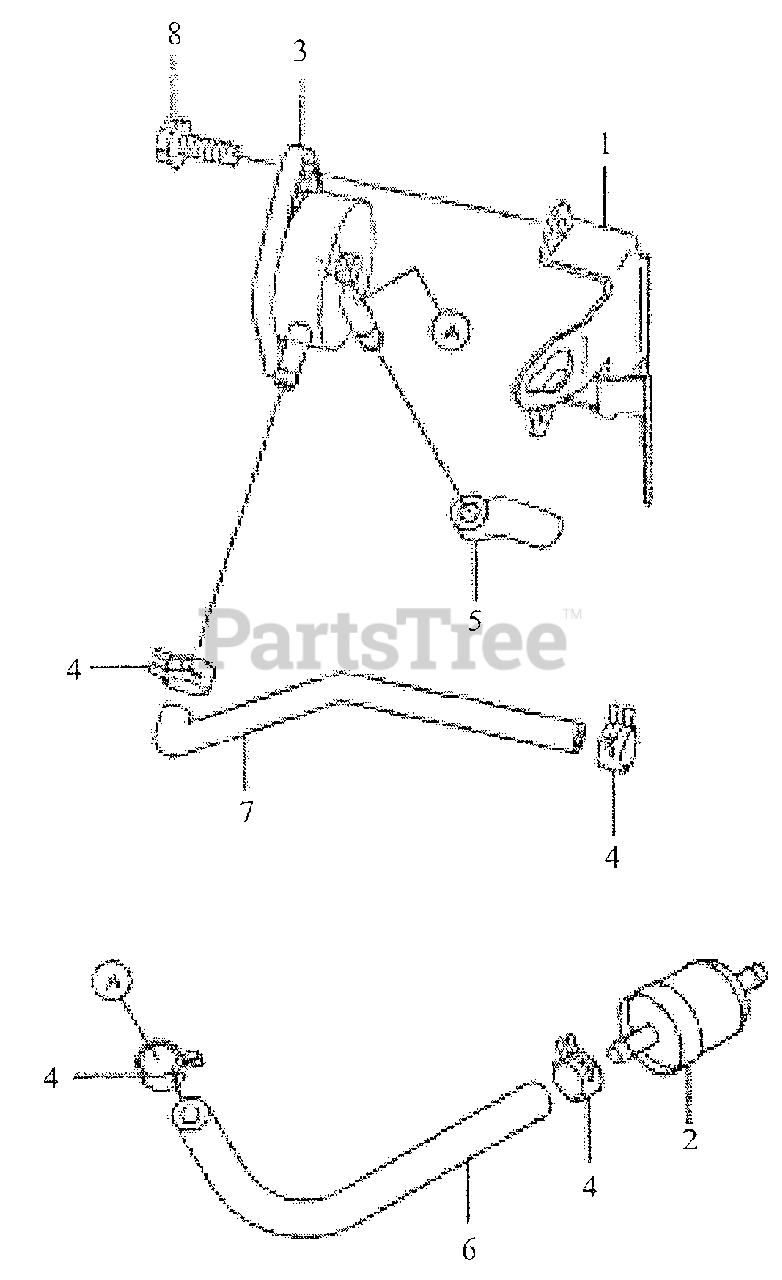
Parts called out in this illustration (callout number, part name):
1	Bracket
2	Filter, Fuel
3	Pump, Fuel
4	Clamp
6	Tube 6.35 x 12.7 x 160
8	Bolt, Flange
